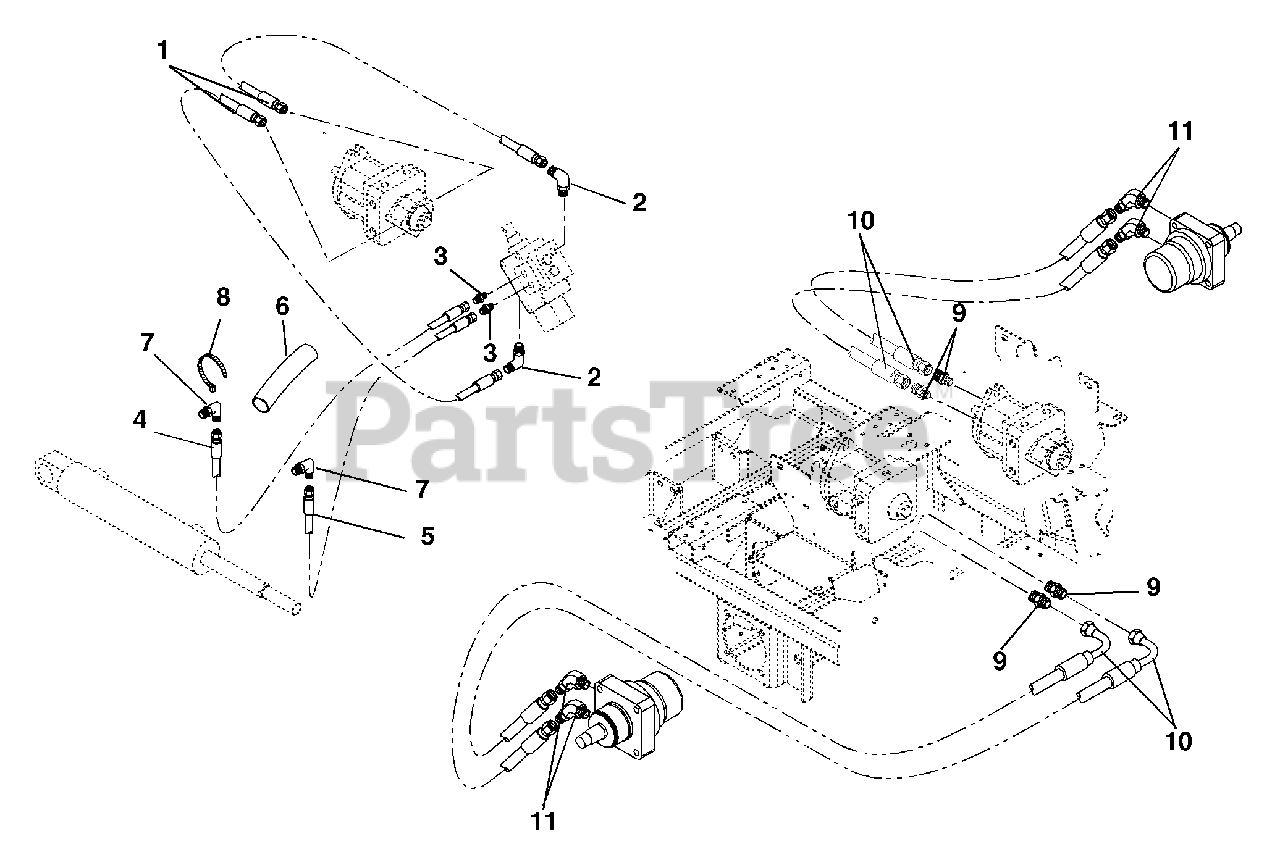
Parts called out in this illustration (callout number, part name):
1	Hose, Hydraulic
2	Hydraulic, Fitting Elbow
4	Hose, Hydraulic
5	Hose, Hydraulic
6	Sleeve Protective 24"
7	Fitting, Hydraulic
8	Cable Tie
9	Adapter, Face Seal 8 x 8 .50 O-Ring
10	Hose, Hydraulic .50
11	Adapter-Hydraulic Steel .875 to .75
